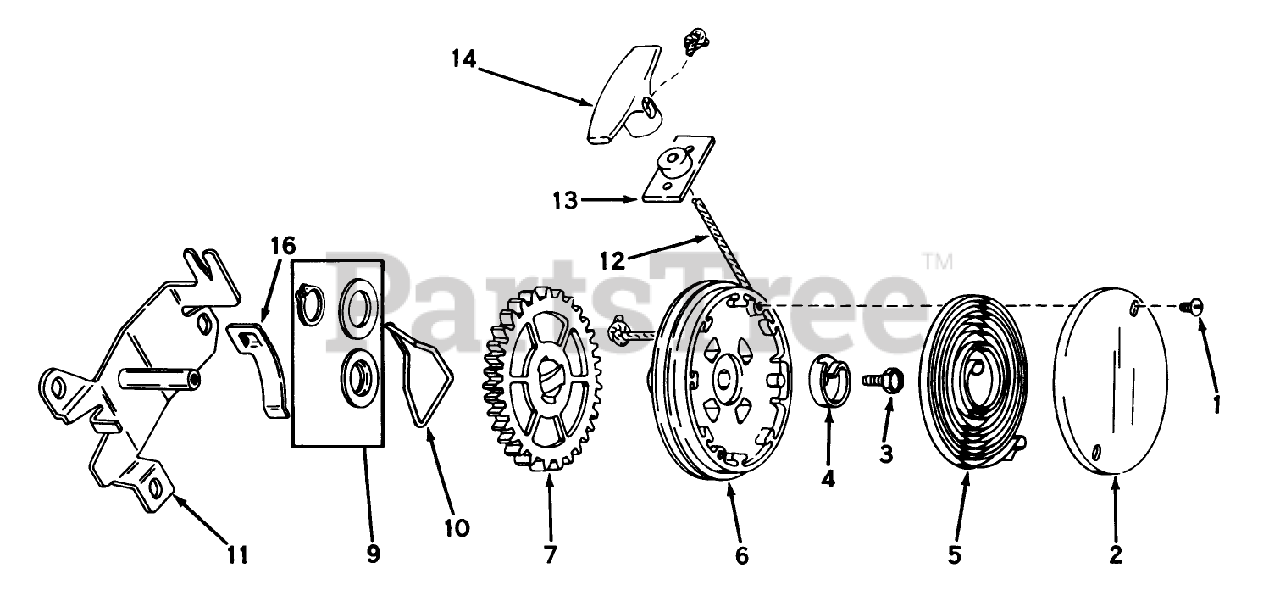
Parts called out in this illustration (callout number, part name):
2	Cover, Spring
3	Screw, Hex Washer Head
4	Hub Spring
5	Spring, Rewind
6	Pulley Assy. (Incl. Ref. #9)
9	Kit, Thrust Wash. & Snap Rg.
11	Bracket Assy. Mounting
12	Rope-Starter
13	Bracket Assy.
14	Handle-Starter
16	Clip Rope
